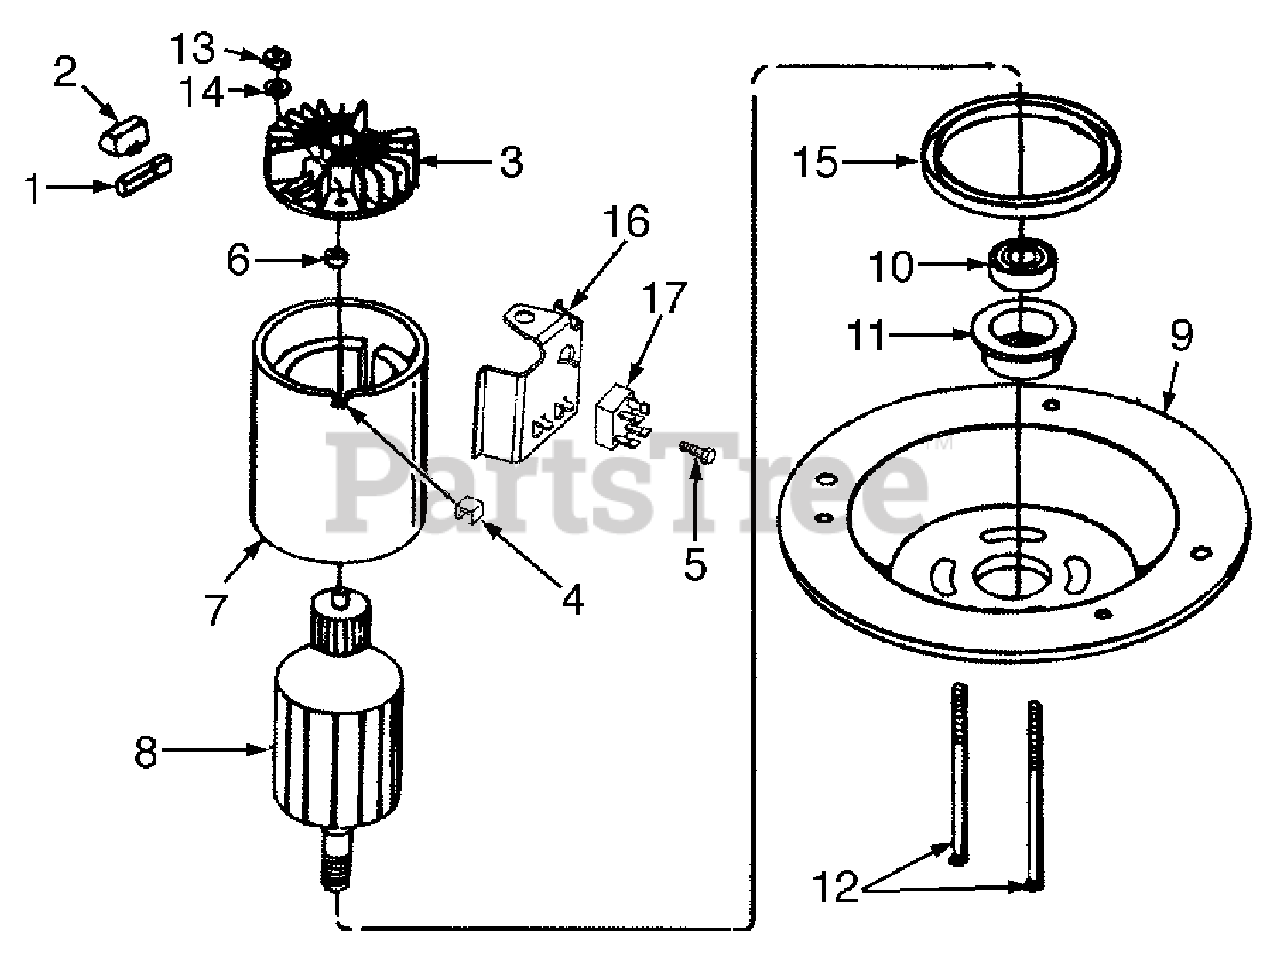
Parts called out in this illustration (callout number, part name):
1	Brush & Liner Assembly.
2	Brush Holder Cap
3	End Shield Assembly. W/plug
4	Insulator Wire (Output)
5	Hex Tap Scr. #10-16 x .62" Lg.
6	Needle Bearing
7	Magnet Housing Assembly
8	Armature Assembly
9	Motor End Plate Assembly
10	Ball Bearing
11	Bearing Adapter
12	Carriage Bolt
13	Hex L-Nut 1/4-20 Thd.
14	Fl. Washer .26" I.D. x .72"
15	Housing Insulator
16	Brkt. Rectifier/Heat Sink
17	Rectifier
